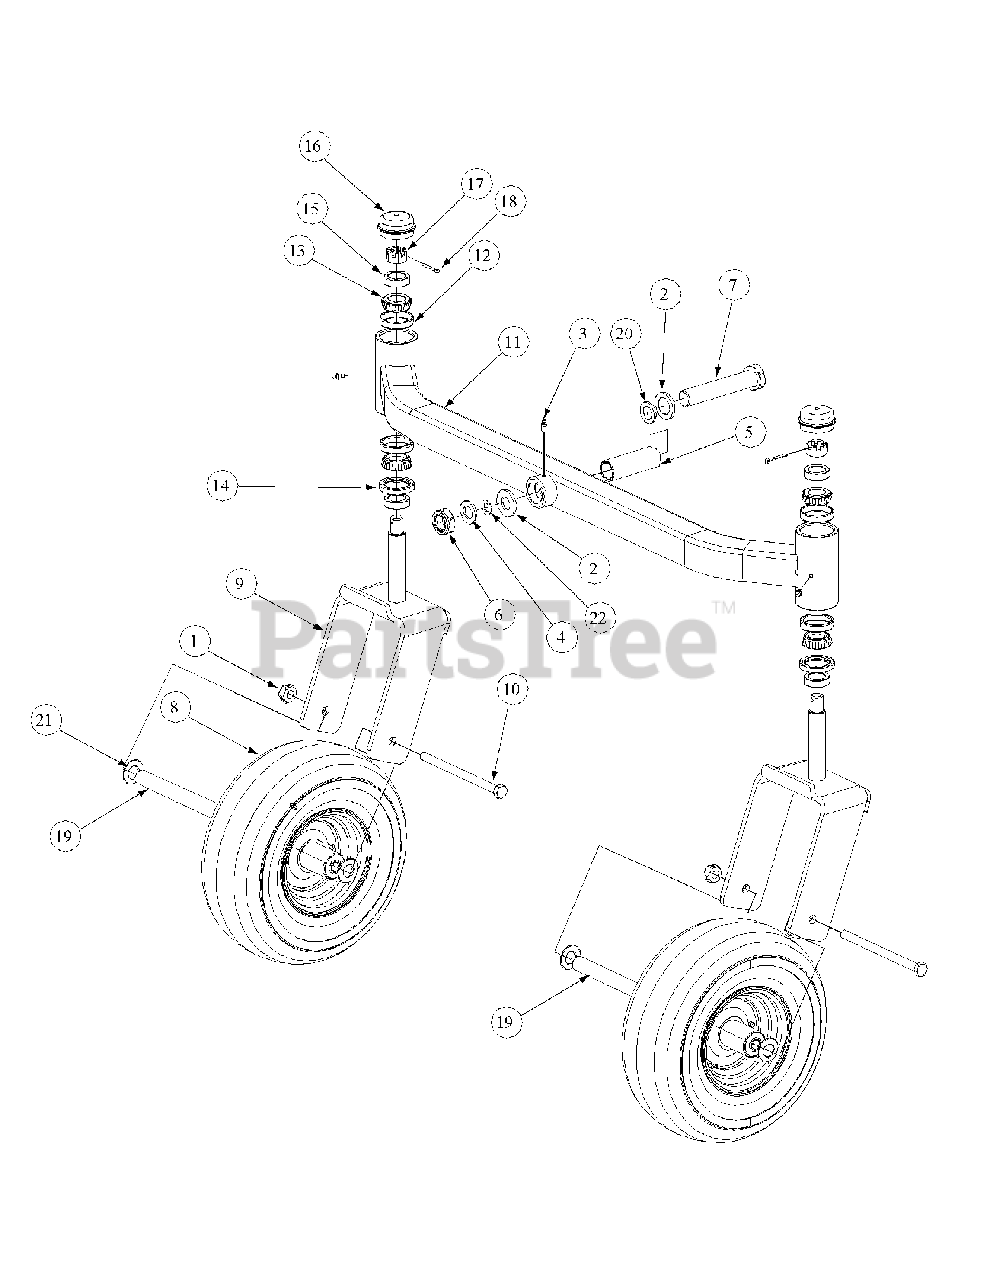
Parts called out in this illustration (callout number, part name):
1	Nut, 1/2-20, Center Lock
2	Bell Washer, 1.25 ID x 2.5 x .157
3	Grease Fitting, 1/4-28 x 3/16
4	Special Washer
5	Spacer, 1.005 ID x 1.25 OD x 3.6
6	Nut, Jam, 1.0-14, Insert Lock
7	Hex Cap Screw, 1-14 x 5.0
8	Wheel, 13 x 6.50 x 6, White includes:
8	Tire 13 x 6.50-6
8	Flange Bearing
8	Cage Roller Bearing
9	Yoke, Caster Wheel
10	HHCS, 1/2-20, 7.50
11	Front Axle Assembly
12	Cup Bearing
13	Bearing Cone
14	Seal
15	Ring Seal
16	Grease Cap, 1.986 OD
17	Slotted Nut, 3/4-16
18	Cotter Pin, 5/32, 1.25
19	Wheel Spacer
20	Flat Washer, 1.25 ID
21	Spacer, .812 ID x .218LG
22	Retainer Extension, Self Locking
